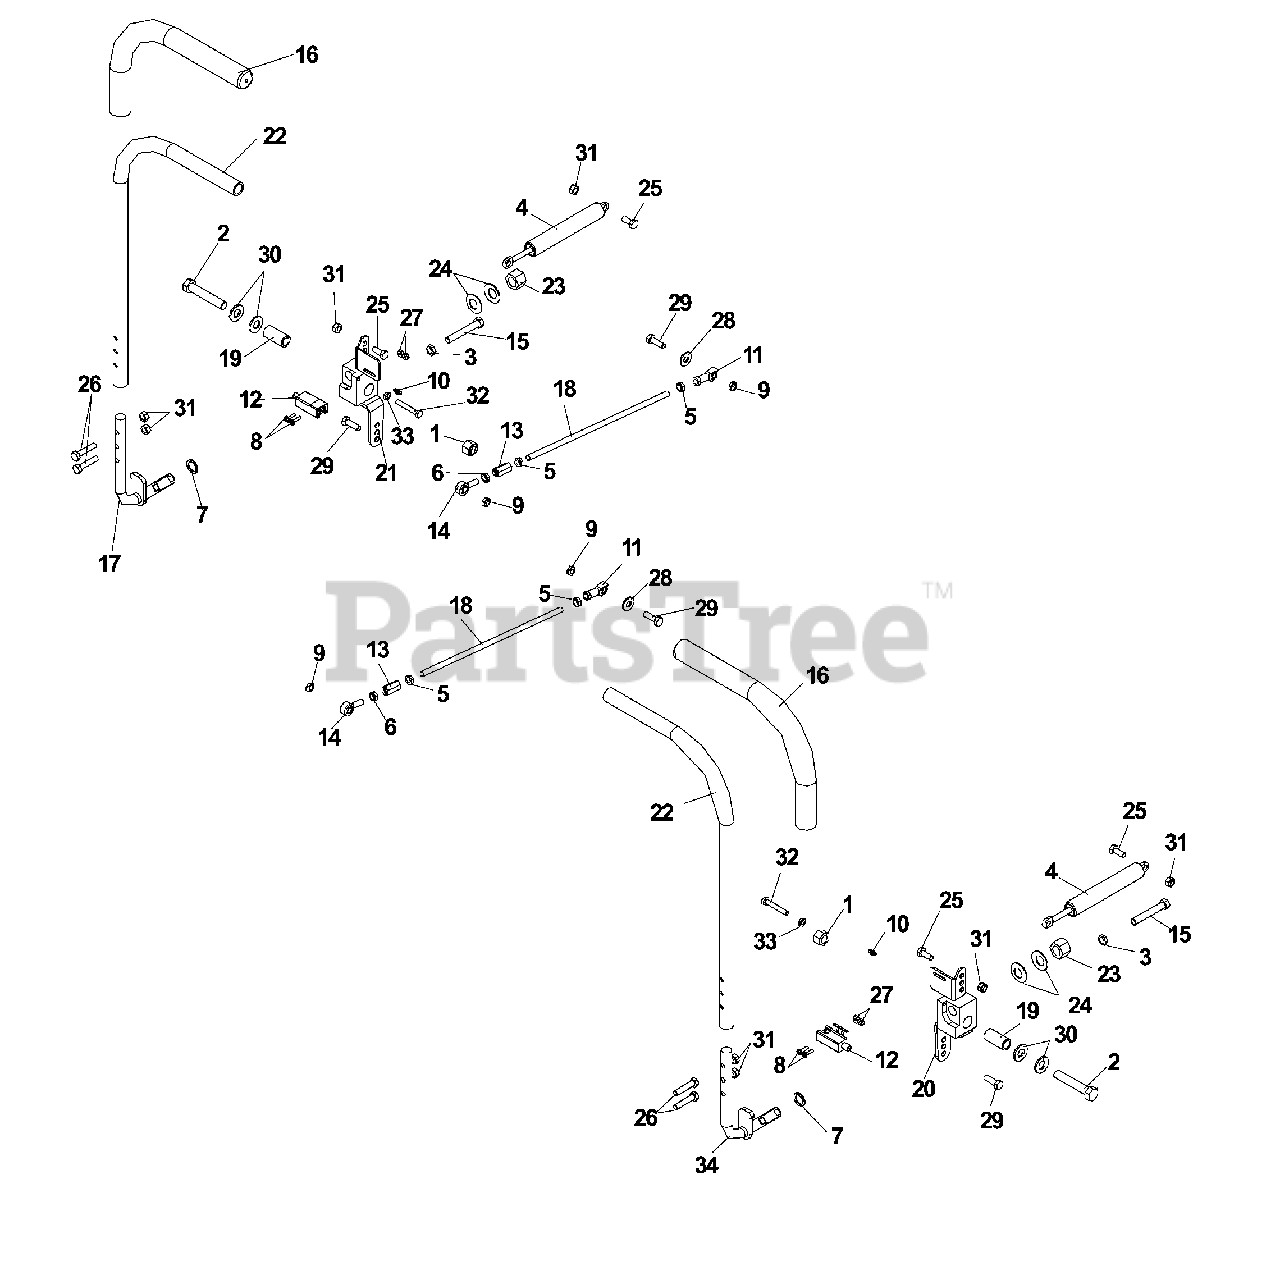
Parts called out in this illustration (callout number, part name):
1	NUT 1/2-13 HEX NYLOC ZD
2	HCS 1/2C X 2 3/4
3	NUT 3/8-16 HEX JAM
4	DAMPENER, DUAL ACTION
5	NUT 5/16-24 UNF HEX JAM
6	5/16 24UNF NUT LH TH
7	WASHER-.626IDX.056TK
8	#10-24X5/8PHIL PANHD
9	5/16-18 THIN PROF NY
10	ZERK, 3/16, DRIVE IN
11	RH ROD END
12	DECK SWITCH
13	ROD END COUPLER
14	ROD.END.LH
15	HHB 3/8-16X2-1/2 GR5ATHD
17	LOWER LVR WLDT.(PLATED)
19	BUSHING
20	PIVOT LH (PLATED)
21	PIVOT RH (PLATED)
22	UPPER LEVER, BLK
23	NUT 5/8-11 NYLOC
24	WASH 5/8 BEVELED DISC SPRING
25	HCS 5/16C X 3/4
26	CAPSCREW 5/16 X 1/1/2 HEX HEAD
27	NUT 10-24 NYLOC
28	FLAT WASHER 5/16 SAE
29	HCS 5/16C X 1
30	WASHER 1/2" FLAT
31	NUT 5/16 NYLOC
32	BOLT 1/4C X 1 3/4
33	NUT 1/4-20 JAM
34	LOWER LEVER WLDT LH PLTD
